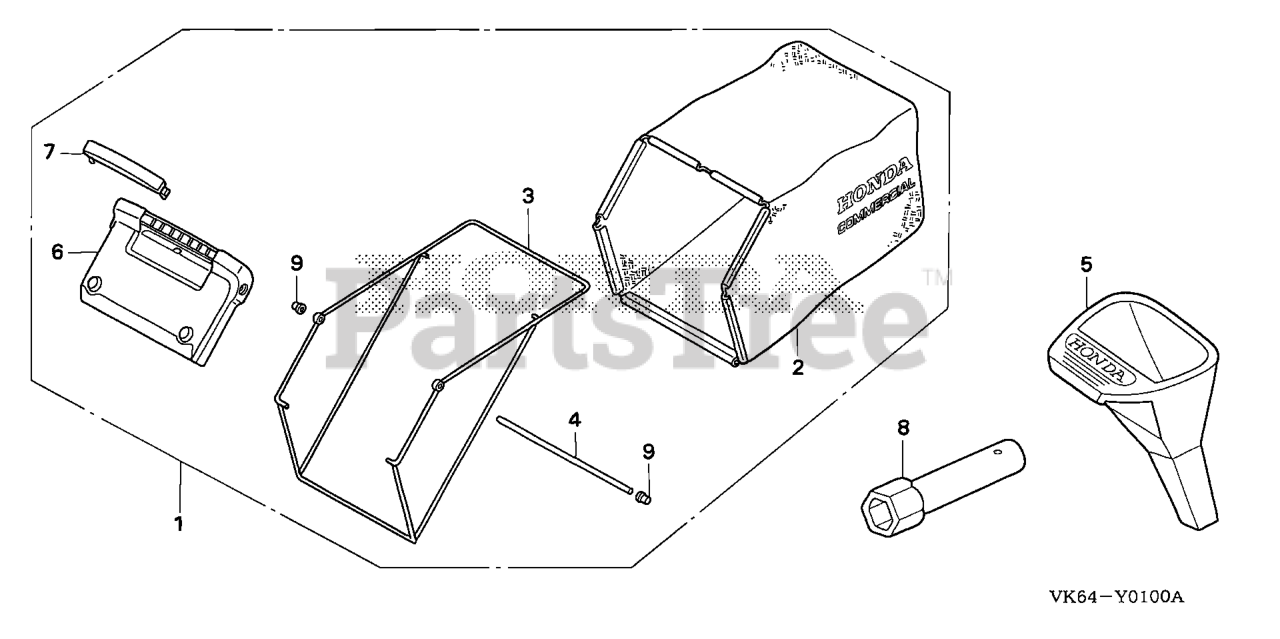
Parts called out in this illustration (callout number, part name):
1	BAG KIT, GRASS
2	FABRIC, GRASS BAG
3	FRAME, BAG (LOWER)
4	JOINT, GRASS BAG
5	FUNNEL, OIL
6	CATCHER, GRASS (UPPER)
7	COVER, GRASS CATCHER GRIP
8	WRENCH, BOX (P21)
9	NUT, PUSH (8MM)
